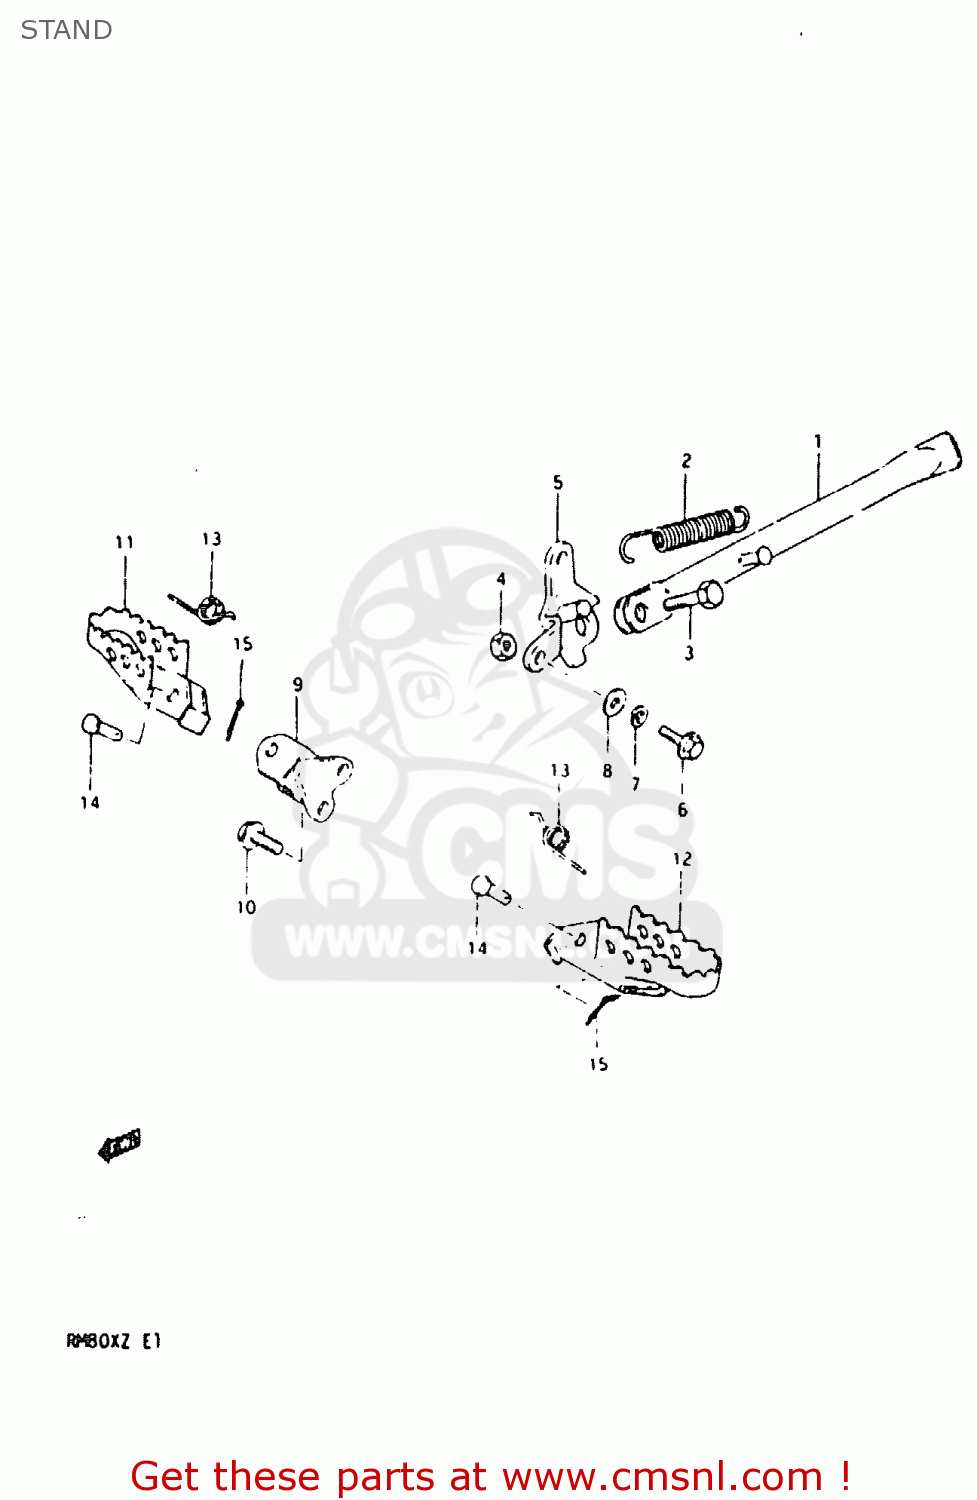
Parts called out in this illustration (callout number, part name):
1	STAND,SIDE
2	SPRING
3	BOLT
4	NUT
5	BRACKET,SIDE STAND
6	BOLT
7	LOCK WASHER
8	WASHER
9	BAR,FRONT FOOTREST
10	BOLT
11	FOOTREST,FRONT,RIGHT
12	FOOTREST,FRONT,LEFT
13	SPRING
14	PIN
15	PIN 20X20
